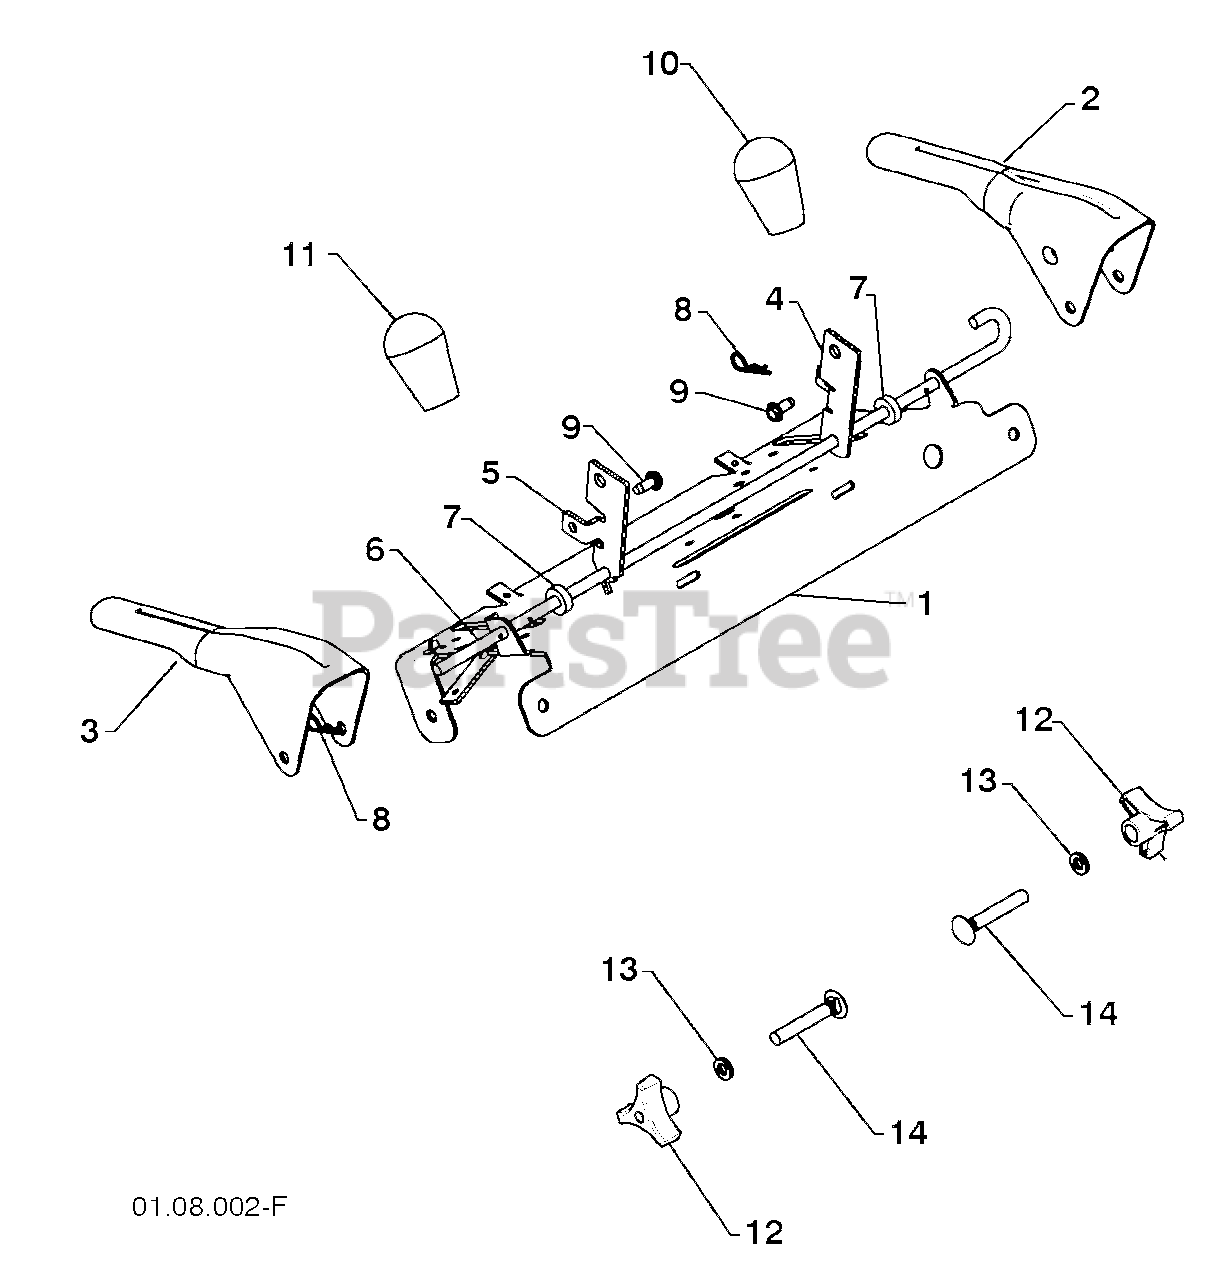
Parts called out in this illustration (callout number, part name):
1	CONTROL PANEL
2	CONTROL LEVER LH
3	CONTROL LEVER RH
4	TRACTION ROD ARM
5	IMPELLER ROD ARM
6	INTERLOCK ROD
8	RETAINER
9	SCREW 1/4-20 X .62
10	KNOB BLACK
11	KNOB RED
12	HANDLE KNOB
13	WASHER 3/8
14	CARRIAGE BOLT 3/8-16 X 2.25
